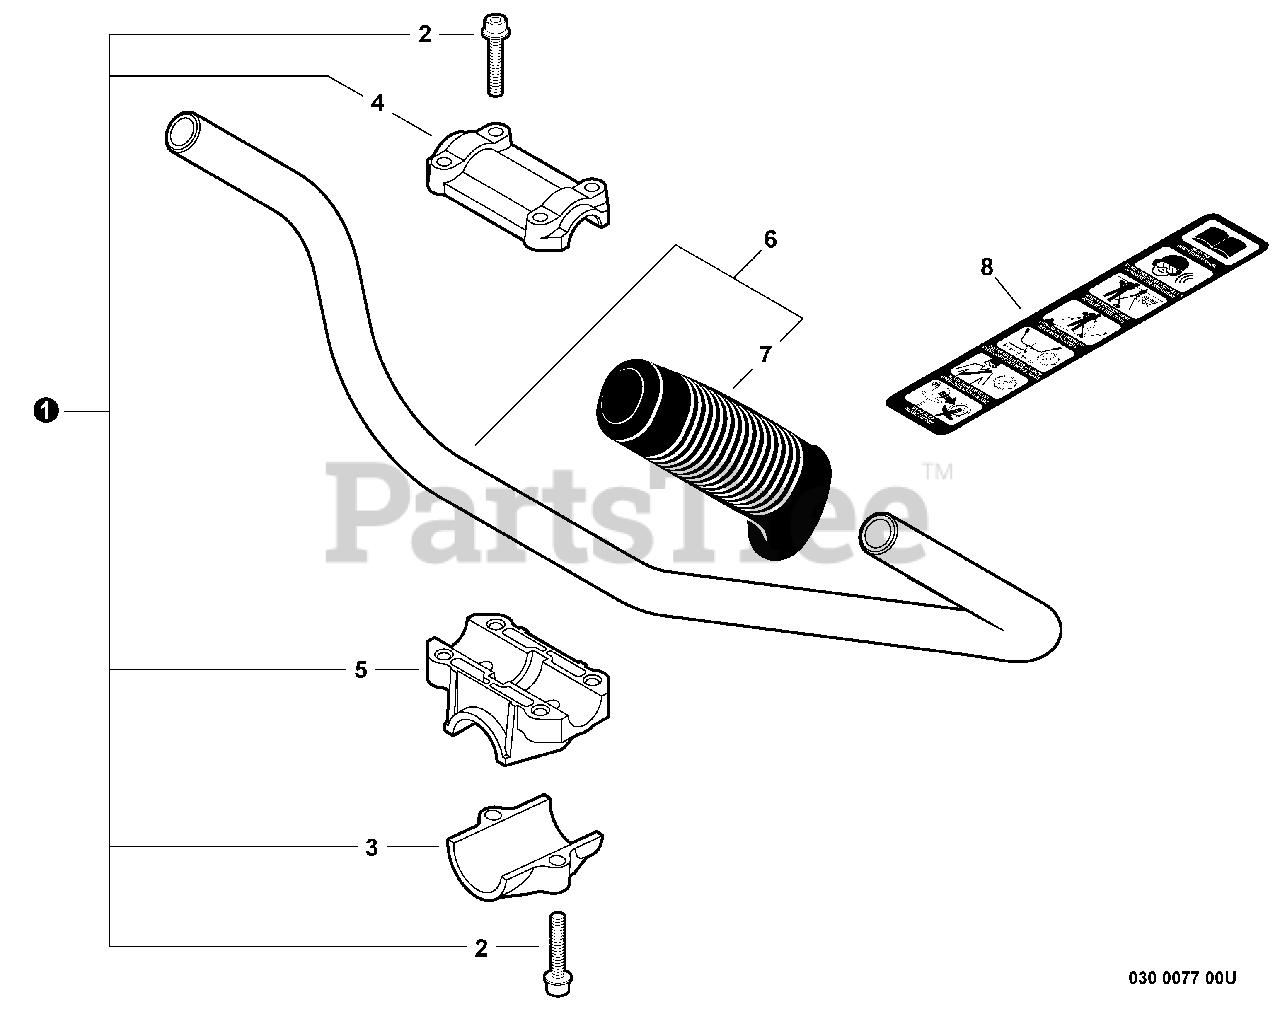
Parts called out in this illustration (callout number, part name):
1	HANDLE BRACKET KIT
2	SCREW - 5X25
3	BRACKET, MOUNTING
4	BRACKET - UPPER
5	BRACKET - LOWER
6	HANDLE ASSY
8	LABEL - CAUTION
